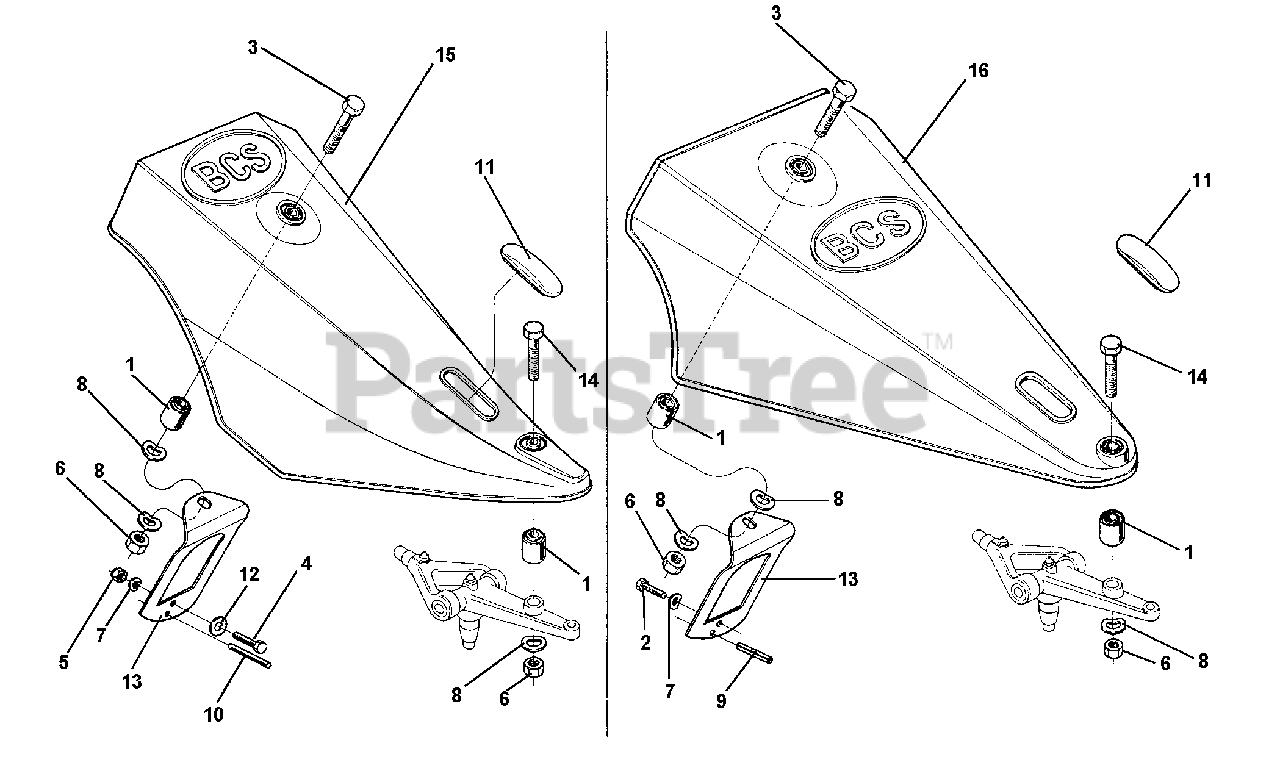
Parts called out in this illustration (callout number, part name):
1	SILENTBLOC 14 X 30 X 25 X 28
2	SCREW M8 X 16
3	SCREW TE M14 X 50
4	SCREW M8 X 50
5	NUT, SELF LOCKING M8
6	NUT, SELF LOCKING M14 LOW
7	WASHER, LOCK 8.4
8	WASHER, LOCK 15
10	PIN, LOCKING 8 X 36
11	OVAL PLUG FOR PROTECTION
12	WASHER 8.5 X 24 X 4
13	HOOK SPRING
14	SCREW, SPECIAL M14
15	FT PROTECTION COMPL. POLYES.
